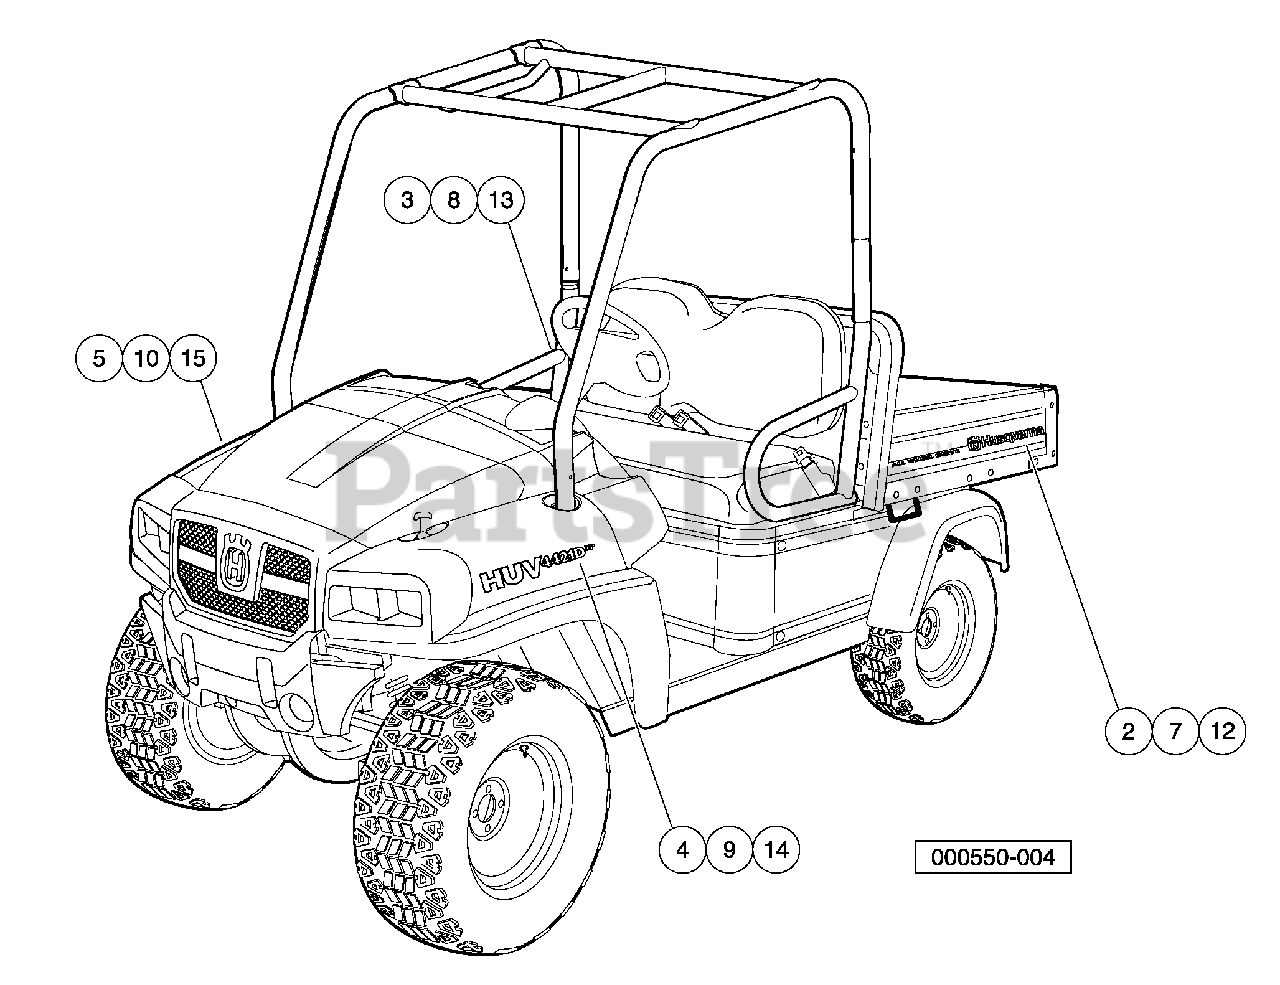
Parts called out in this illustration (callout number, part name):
2	Decal, Bed, Huv, Moff, Ds
3	Decal, Bed, Huv, Moff, Ps
4	Decal, Huv, 4421dxp, Moff, Ds
5	Decal, Huv, 4421dxp, Moff, Ps
7	Decal, Bed, Huv, Orange, Ds
8	Decal, Bed, Huv, Orange, Ps
9	Decal,huv 4421dxp, Orange, Ds
10	Decal,huv 4421dxp, Orange, Ps
11	Instl,decal,huv4421dxp,olv Grn
12	Decal, Bed, Huv, Olv Grn, Ds
13	Decal, Bed, Huv, Olv Grn, Ps
14	Decal,huv 4421dxp, Olv Grn, Ds
15	Decal,huv 4421dxp, Olv Grn, Ps
